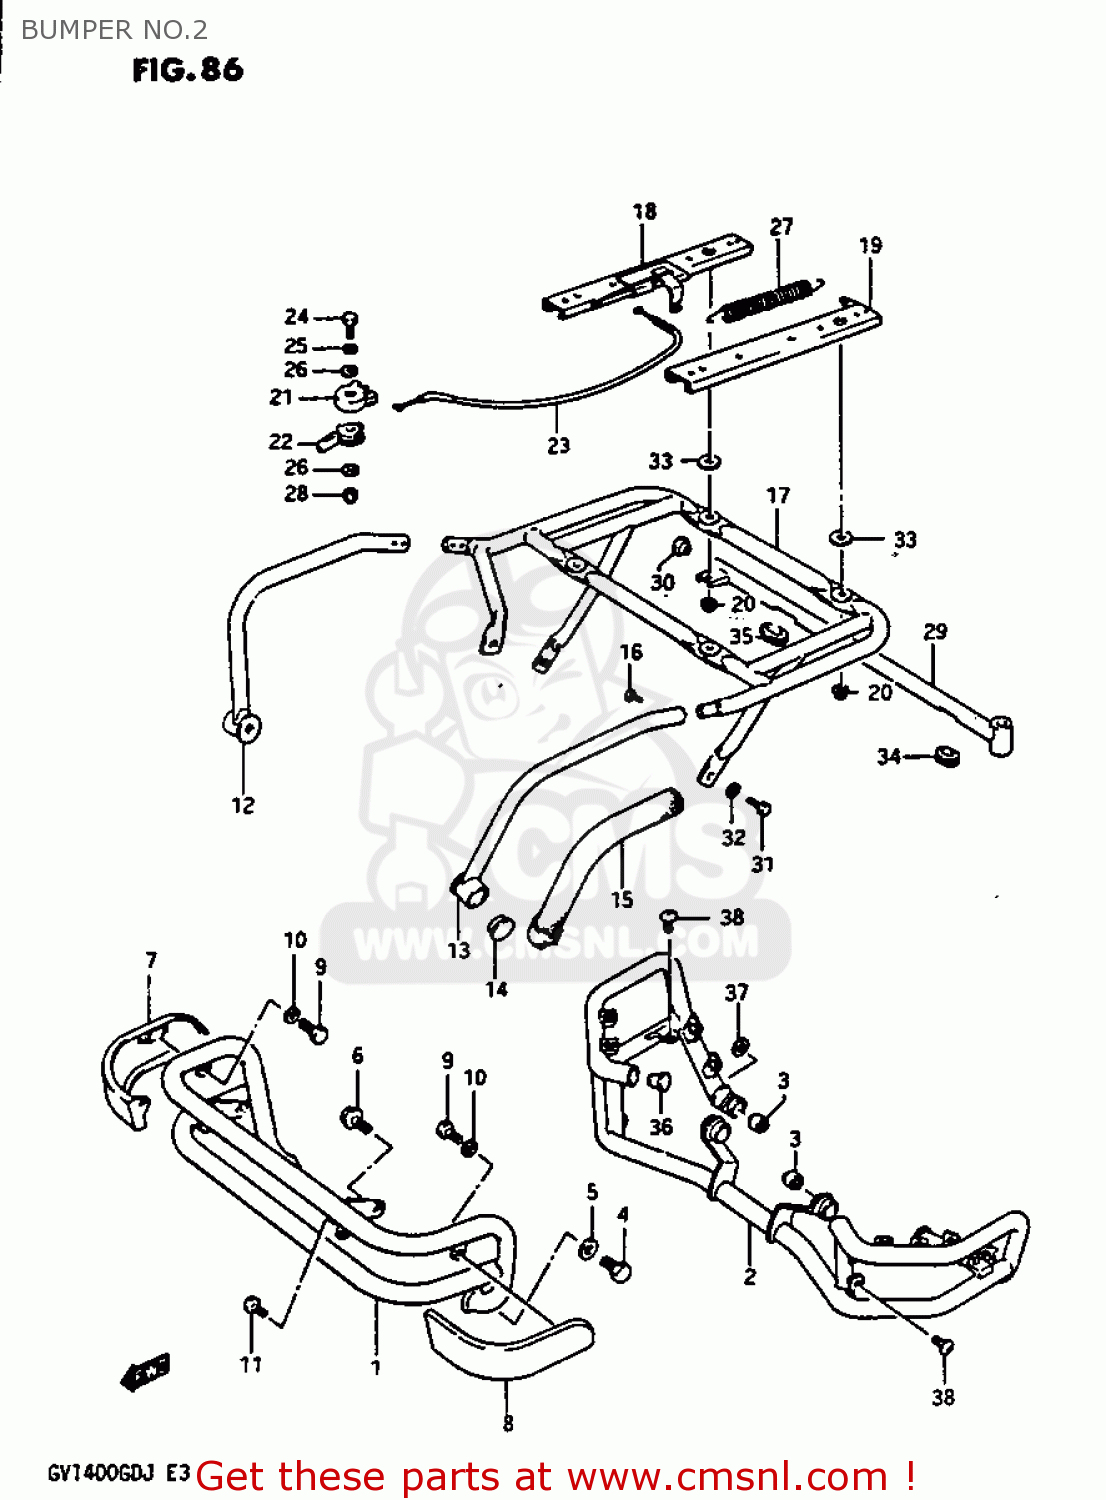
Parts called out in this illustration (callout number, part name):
1	BAR COMP,ACCESSORY
2	BAR SET,ACCESSORY
3	BUSH
4	BOLT
5	WASHER
6	BOLT
7	COVER COMP,ACCESSORY B
8	COVER COMP,ACCESSORY B
9	BOLT
10	WASHER,LOCK
11	SCREW 6X12
12	PIPE,CO-RIDER GRIP,RIGHT
13	PIPE,CO-RIDER GRIP,LEFT
14	CAP,PIPE CO-RIDER GRIP
15	GRIP,CO-RIDER
16	SCREW
17	CARRIER,TRAVEL TRUNK
18	RAIL COMP,TRAVEL TRUNK
19	RAIL COMP,TRAVEL TRUNK
20	NUT
21	BODY COMP,SLIDER LEVER
22	LEVER,RAIL COMP,SLIDER
23	CABLE ASSY,SLIDE RAIL COMP
24	BOLT
25	WASHER
26	WASHER(6.5X18X1)
27	SPRING
28	NUT 6MM
29	HOLDER,ANTENNA BAR
30	CAP(OD:20)
31	BOLT
32	LOCK WASHER
33	WASHER (6.5X24X1.6)
34	GROMMET
35	GROMMET
36	CAP,ACCESSORY BAR
37	WASHER (8.2X24X1.6)
38	SCREW
